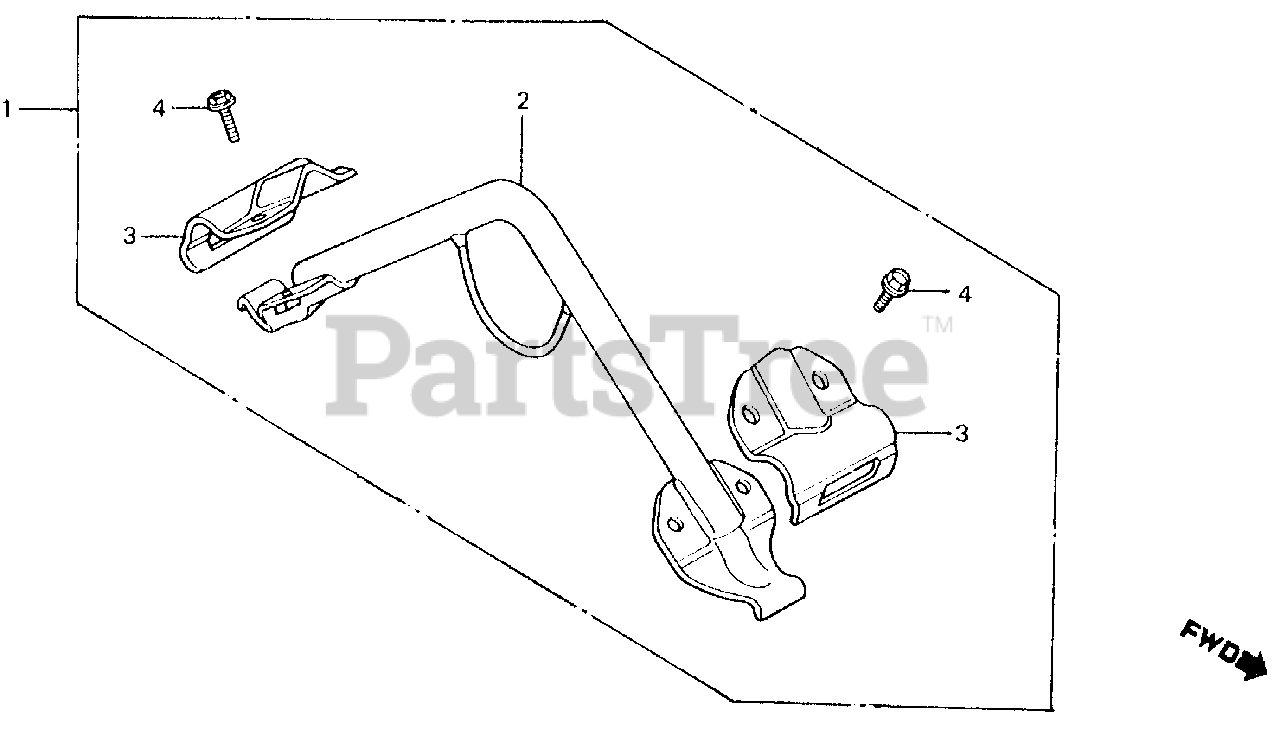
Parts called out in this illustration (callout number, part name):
1	HANGER KIT
2	HANGER
3	BRACKET, HANGER (UPPER)
4	BOLT, FLANGE (8X16)
